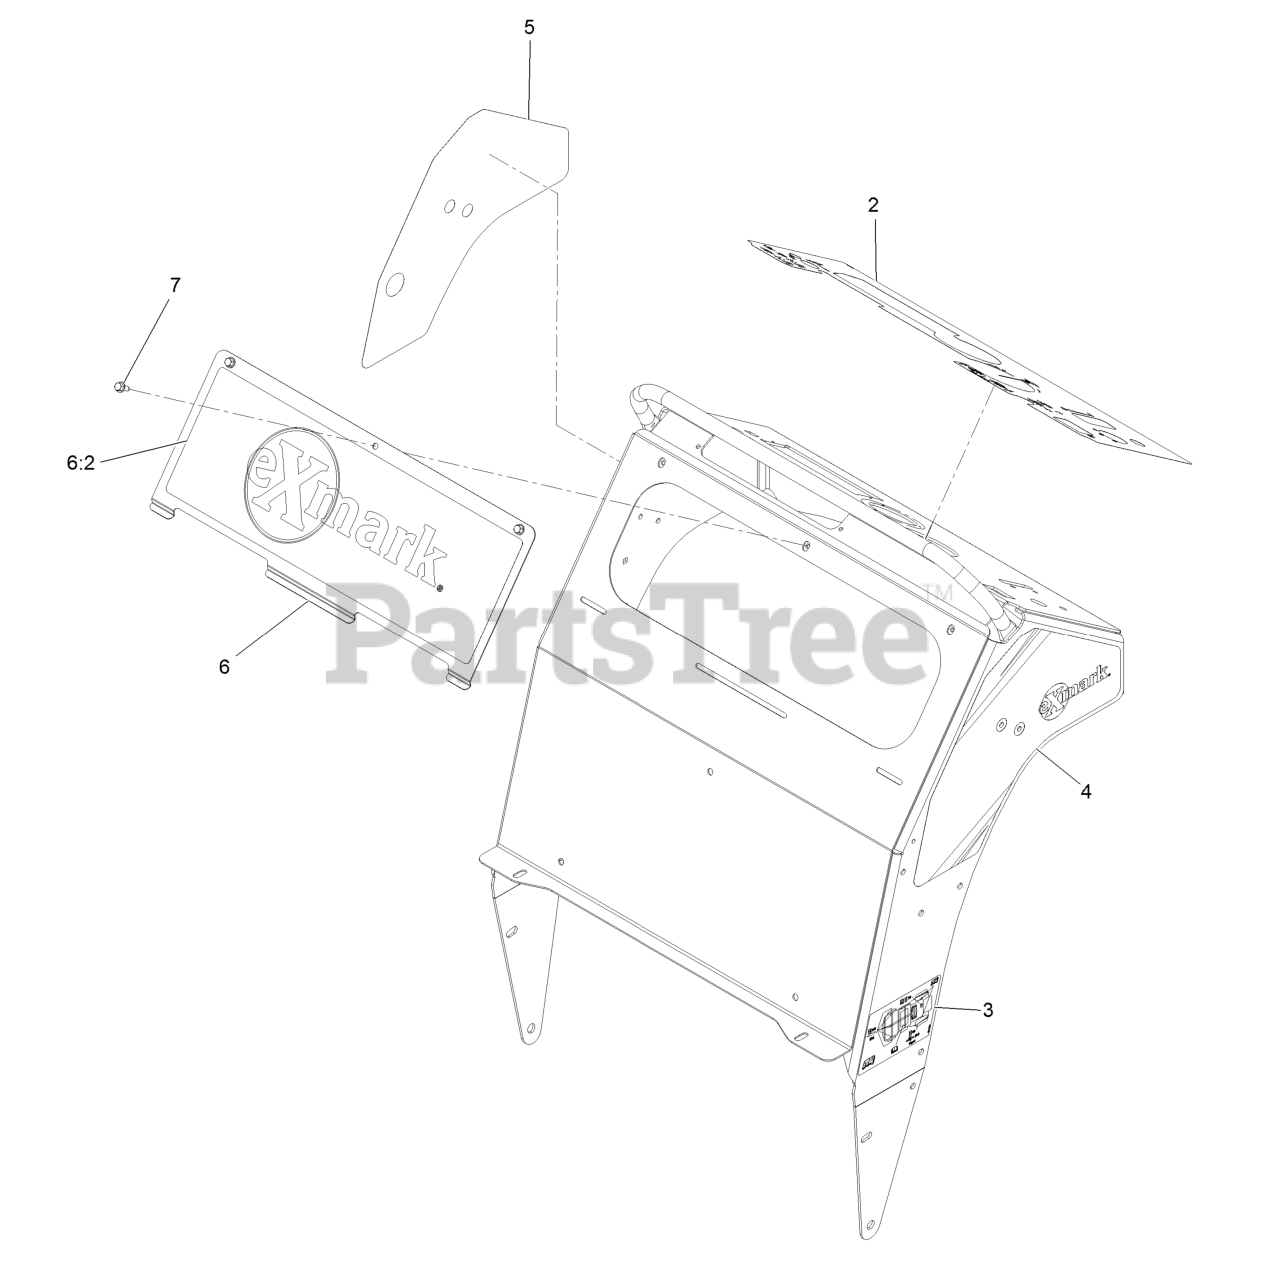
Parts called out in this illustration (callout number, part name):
2	Decal-Control
3	Decal-Service Aid
4	Decal-LH Side Panel
5	Decal-RH Side Panel
6	Access Panel W/ Decal
6:2	Decal-Exmark Front Panel
7	Screw-HWH 1/4-20 X .62
